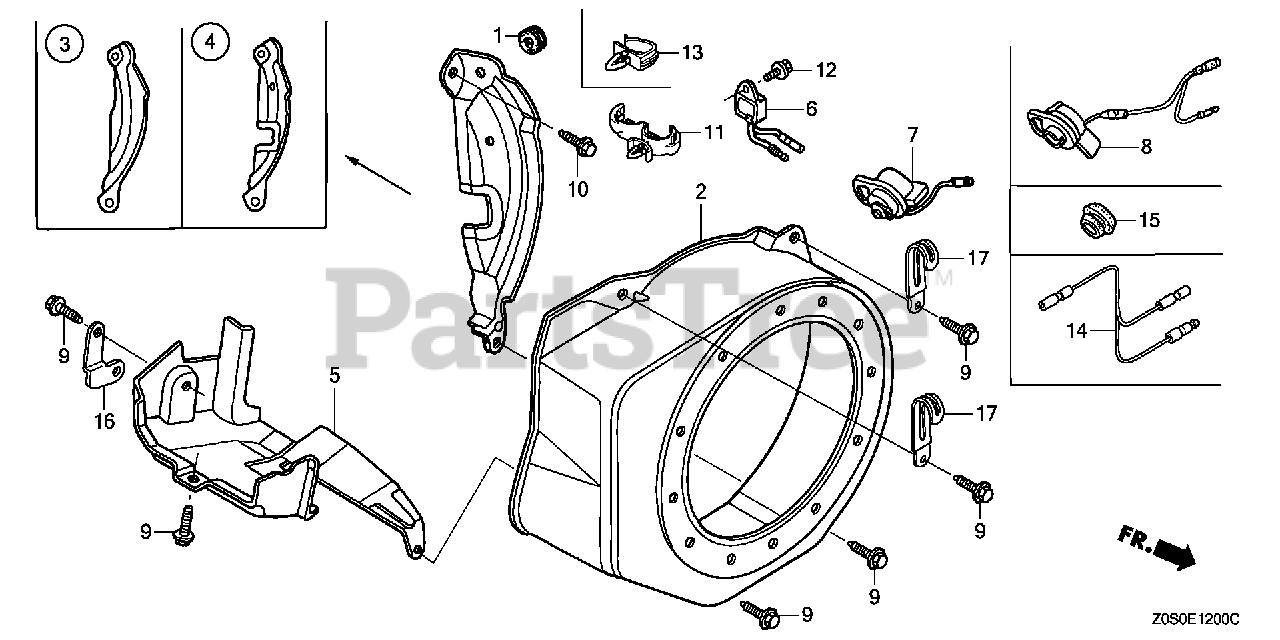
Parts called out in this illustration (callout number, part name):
1	GROMMET, ADJUSTING COVER
2	COVER, FAN *NH1* (BLACK)
2	COVER, FAN *R280* (POWER RED)
3	PLATE, SIDE (STD)
9	BOLT, FLANGE (6X12) (CT200)
10	BOLT, FLANGE (6X20) (CT200)
15	GROMMET, DRAIN HOLE
17	CLIP, WIRE HARNESS
